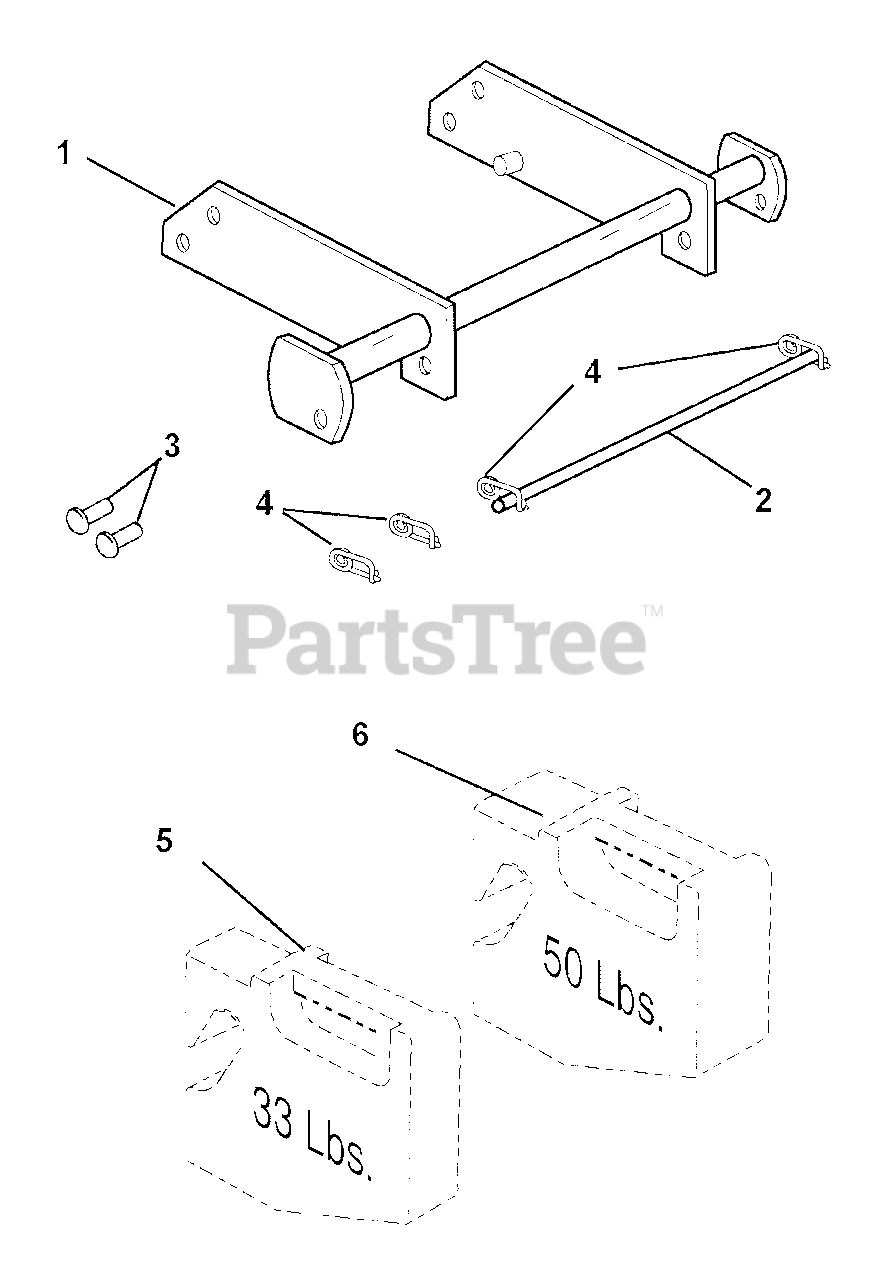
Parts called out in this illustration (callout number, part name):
1	HITCH
2	ROD, Locking
3	PIN, Clevis, 5/8 x 2-1/4
4	CLIPS, Safety
5	WEIGHT, Suitcase, 33 lbs.
6	WEIGHT, Suitcase, 50 lbs.
